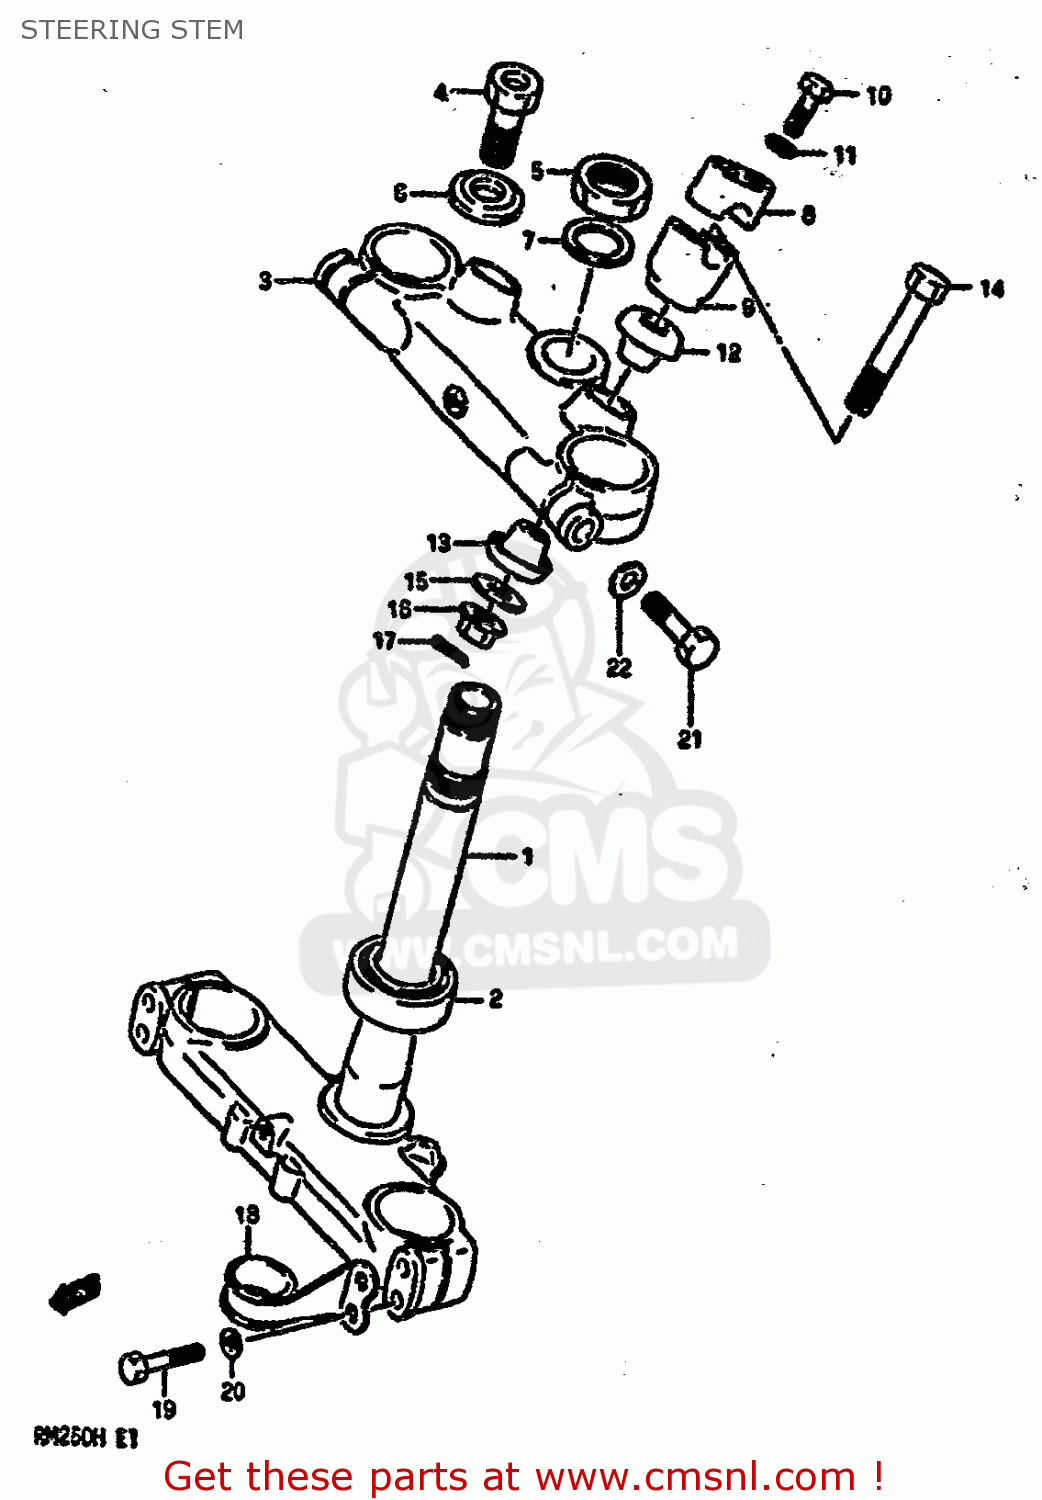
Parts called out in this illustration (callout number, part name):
1	STEM,STEERING
2	BEARING
3	HEAD,STEERING STEM
4	BOLT
5	NUT,STEERING STEM
6	WASHER
7	WASHER
8	HOLDER,HANDLEBAR
9	HOLDER,HANDLE LWR
10	BOLT
11	WASHER,LOCK
12	DAMPER,UPR
13	DAMPER,LWR
14	BOLT,HANDLE HOLDER
15	WASHER,HANDLEBAR HOLDER
16	NUT
17	COTTER PIN
18	CLIP
19	BOLT 8X40
20	WASHER,LOCK
21	BOLT
22	LOCK WASHER
